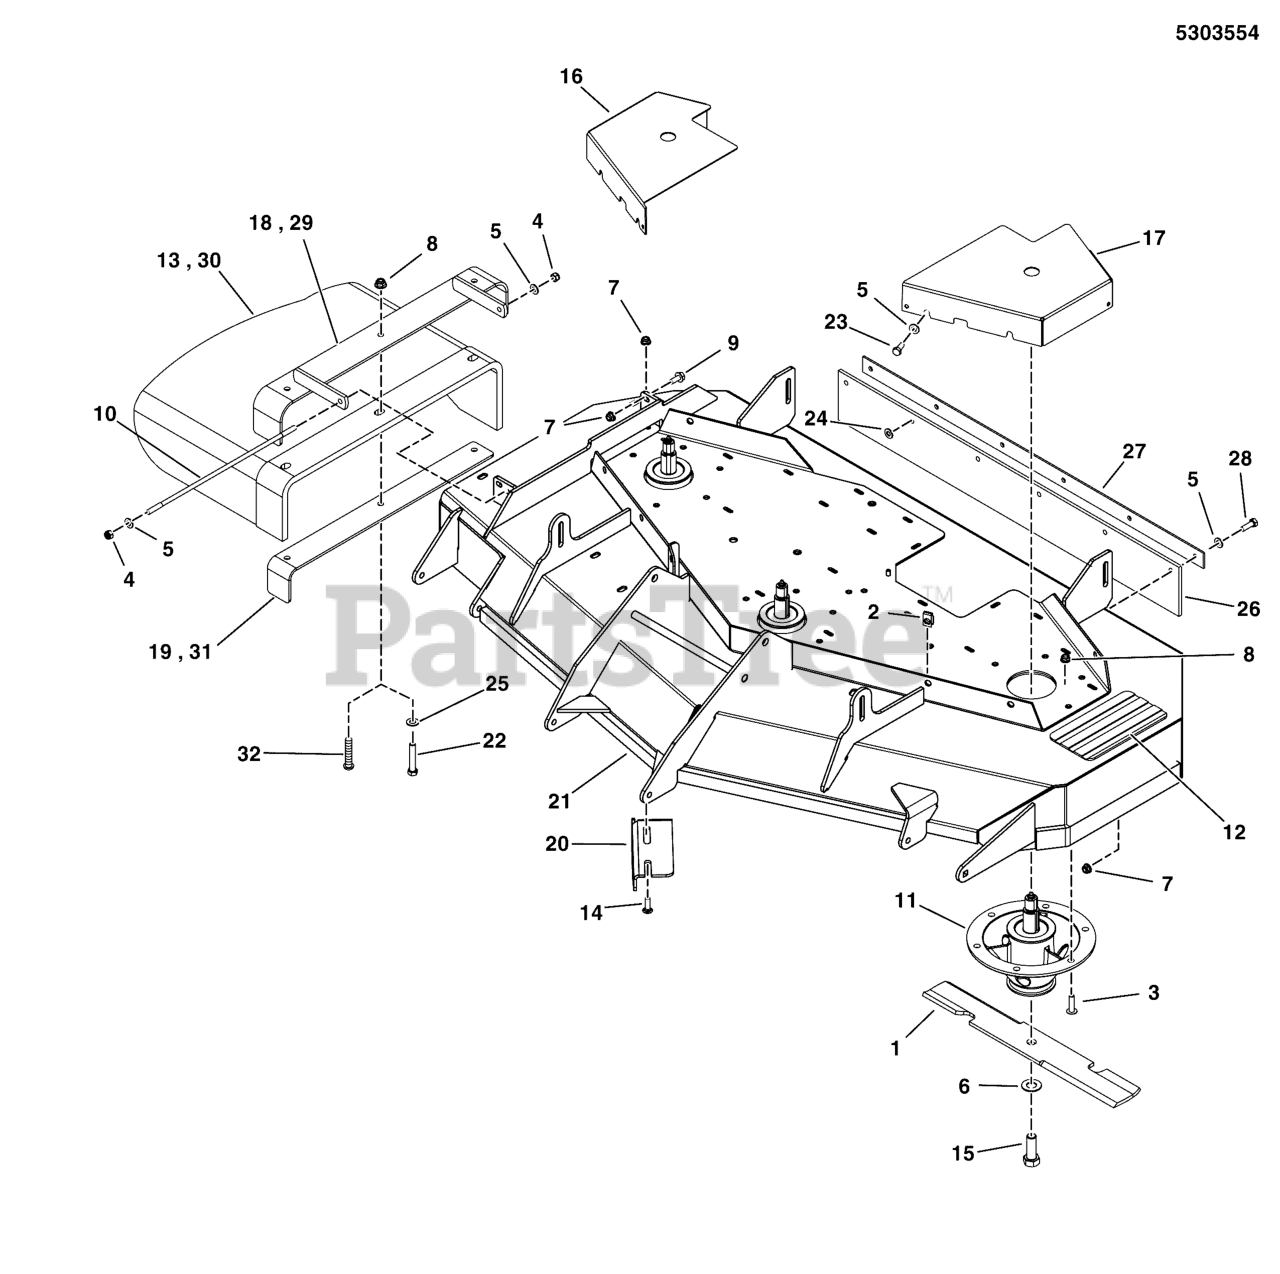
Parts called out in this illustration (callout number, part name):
1	BLADE SET, 52 SLOPE DECK (SV)
2	BODY CLIP, 5/16-18-7GA MATERIAL
3	BOLT, 3/8-16 X 1, FLANGE, GD 5, CZ
4	NUT, 5/16-24 HEX NYLON LOCK
5	WASHER, 5/16" SAE
6	WASHER, BLADE BOLT, 9/16" F436, CZ
7	NUT, 5/16-18 HEX NYLOCK FLANGE
8	NUT, 3/8-16 HEX NYLOCK FLANGE
9	BOLT, 5/16-18 X 3/4 GD5
10	ROD, MOUNT, CHUTE 61, CZ
11	SPINDLE ASSM, CAST IRON 8.0-6 BOLT
12	SAFETY WALK, 4.00 X 7.50
13	CHUTE, Discharge
14	BOLT, 5/16-18 X 3/4, CARRIAGE
15	BOLT, 5/8-11 X 1-3/4 GD8
16	GUARD, 52 DECK, RH - RED
17	GUARD, 52" DECK - LH - RED
18	WELD, FRAME CHUTE, 52 - BLK
19	SUPPORT, DISCHARGE CHUTE, 52 - BLK
20	PLATE, DEFLECTOR, 52 DECK - BLK
21	DECK SHELL W/ DECALS, 52, S150XT (5411156D)
21	DECK SHELL W/ DECALS, 52, S150XT-DOM (5413377D)
22	BOLT, 3/8-16 X 1-1/4" GD5 CZ
23	BOLT, 5/16-18 X 3/4 GD5
24	5/16 PUSH-ON NUT RETAINER, STL, CZ
25	WASHER, 3/8 SAE
26	FLAP, STRIPER, 52 DECK
27	PLATE, SUPPORT - BLK
28	BOLT, 5/16-18 X 1 GD5 YZ
29	WELD, MOUNT, DISCHARGE CHUTE - BLK
30	CHUTE, RUBBER DISCHARGE
31	SUPPORT, DISCHARGE CHUTE - BLK
32	BOLT, 3/8-16 X 1-1/2, CARRIAGE, GD5, CZ
